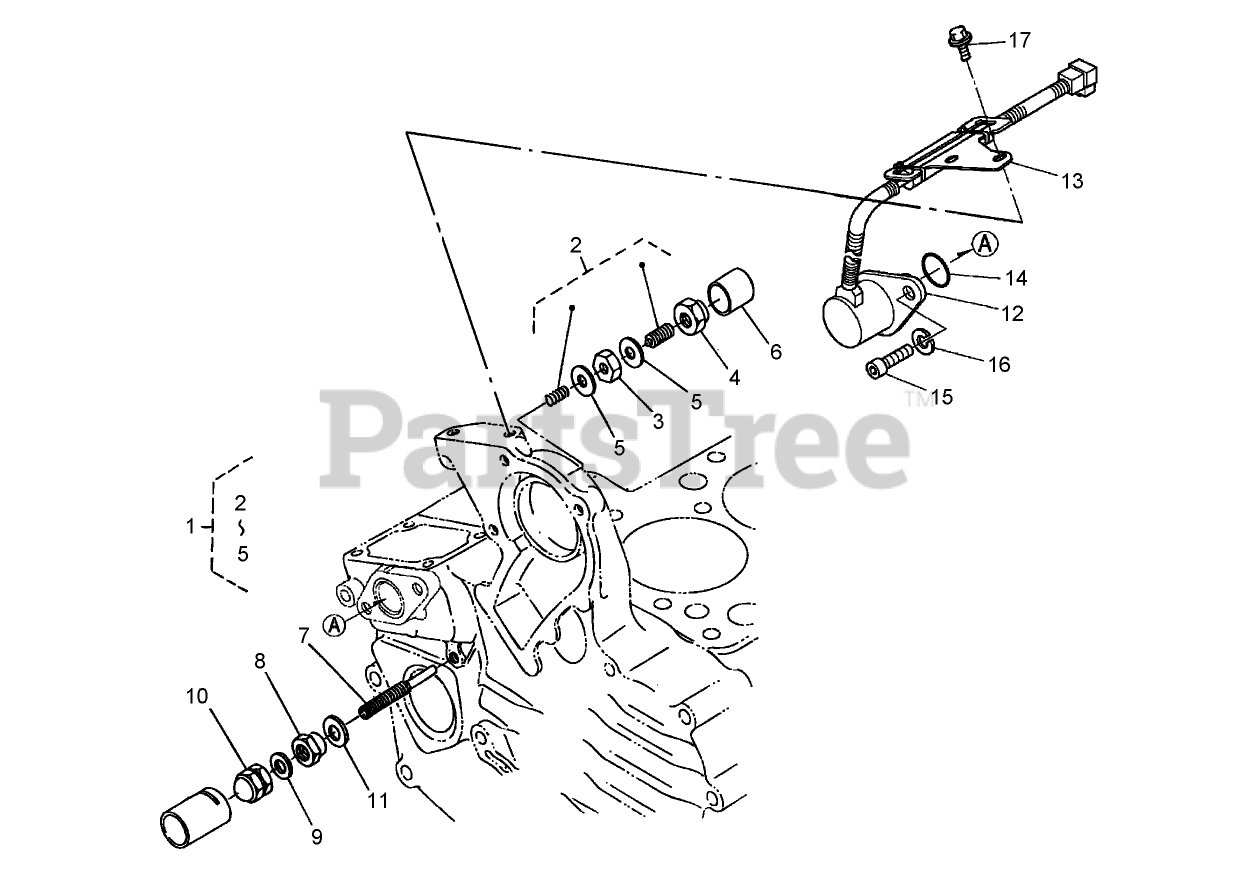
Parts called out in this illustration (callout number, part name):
1	IDLE APPARATUS ASM
2	ADJUSTING BOLT ASM
4	NUT-CAP
5	GASKET
7	BOLT-ADJUSTING
8	NUT-LOCK
9	GASKET
10	NUT-CAP
11	GASKET
12	SOLENOID-STOP
13	STAY-COMMANDER, COIL
14	O-RING
15	BOLT-HSH
16	WASHER-SPRING
17	BOLT-FLANGE
